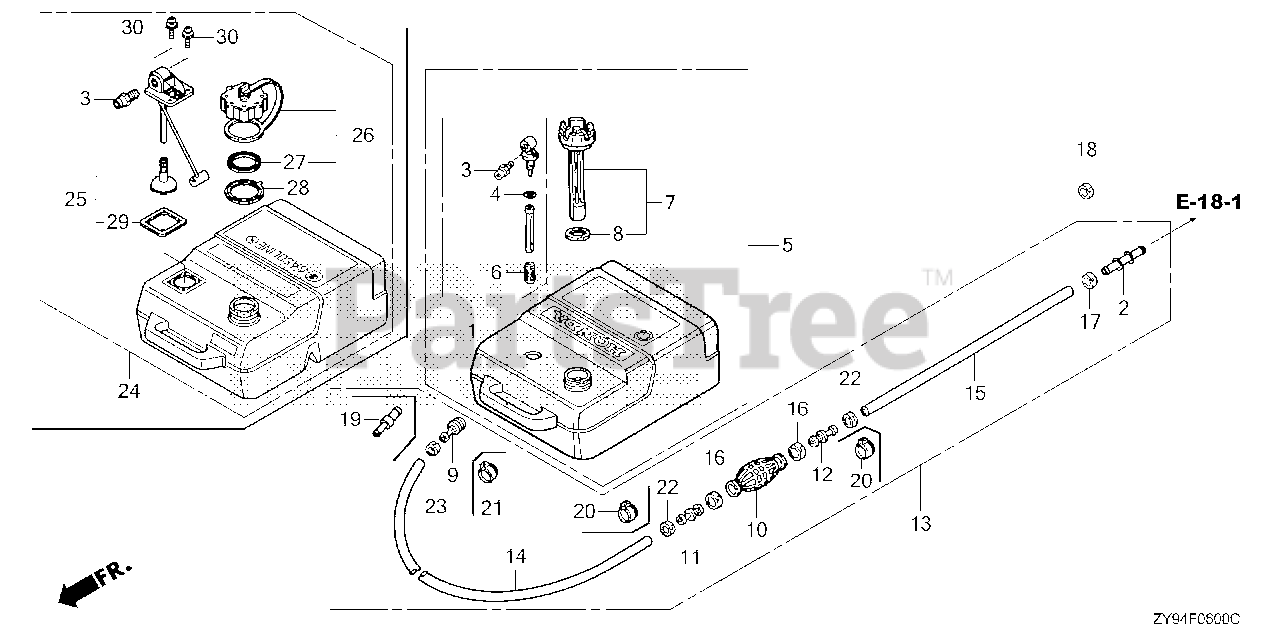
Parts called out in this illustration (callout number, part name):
1	JOINT ASSY., FUEL Use from Frame SN 1300962.
2	JOINT, FUEL TUBE
3	FITTING, QUICK DISCONNECT Use from Frame SN 1205705.
4	O-RING Use from Frame SN 1300962.
5	TANK ASSY., FUEL
6	FILTER, FUEL
7	CAP, FUEL FILLER
8	GASKET, FUEL CAP
9	CONNECTOR, FUEL (CONNECTOR TYPE)
10	BULB, PRIMER
11	VALVE, IN.
12	VALVE, OUTLET
13	TUBE ASSY., FUEL TANK (JOINT TYPE)(FKM)
13	TUBE ASSY., FUEL (JOINT TYPE)
13	TUBE, FUEL TANK
13	TUBE ASSY., FUEL TANK (CONNECTOR TYPE)
14	TUBE, FUEL LONG (7.3X2000) (CONNECTOR TYPE)
14	TUBE, FUEL LONG (7.3X2000)
14	TUBE, FUEL SHORT (6.3X500) (CONNECTOR TYPE)
14	TUBE, FUEL SHORT (7.3X500) (CONNECTOR TYPE)
14	TUBE, FUEL SHORT (CONNECTOR TYPE)
15	TUBE, FUEL LONG (7.3X2000) (CONNECTOR TYPE)
15	TUBE, FUEL LONG (7.3X2000)
15	TUBE, FUEL SHORT (6.3X500) (CONNECTOR TYPE)
15	TUBE, FUEL SHORT (7.3X500) (CONNECTOR TYPE)
15	TUBE, FUEL SHORT (CONNECTOR TYPE)
16	BAND, TUBE CLIP (20MM)
17	BAND, TUBE CLIP (12.5MM)
18	BAND, TUBE CLIP (12.5MM)
19	JOINT, FUEL TUBE (JOINT TYPE)
20	CLAMP, FUEL TUBE (CONNECTOR TYPE)
20	CLAMP, FUEL TUBE (14.0) (CONNECTOR TYPE)
21	CLAMP, FUEL TUBE (CONNECTOR TYPE)
21	CLAMP, FUEL TUBE (14.0) (CONNECTOR TYPE)
22	BAND, TUBE CLIP (12.5MM)
23	BAND, TUBE CLIP (12.5MM)
24	TANK ASSY., FUEL
25	FILTER KIT, FUEL
26	CAP, FUEL FILLER
27	GASKET, FUEL CAP
28	RETAINER, PRESSURE RELIEF
29	GASKET, FUEL PICK-UP
30	BOLT-WASHER (5MM) (SEAL)
